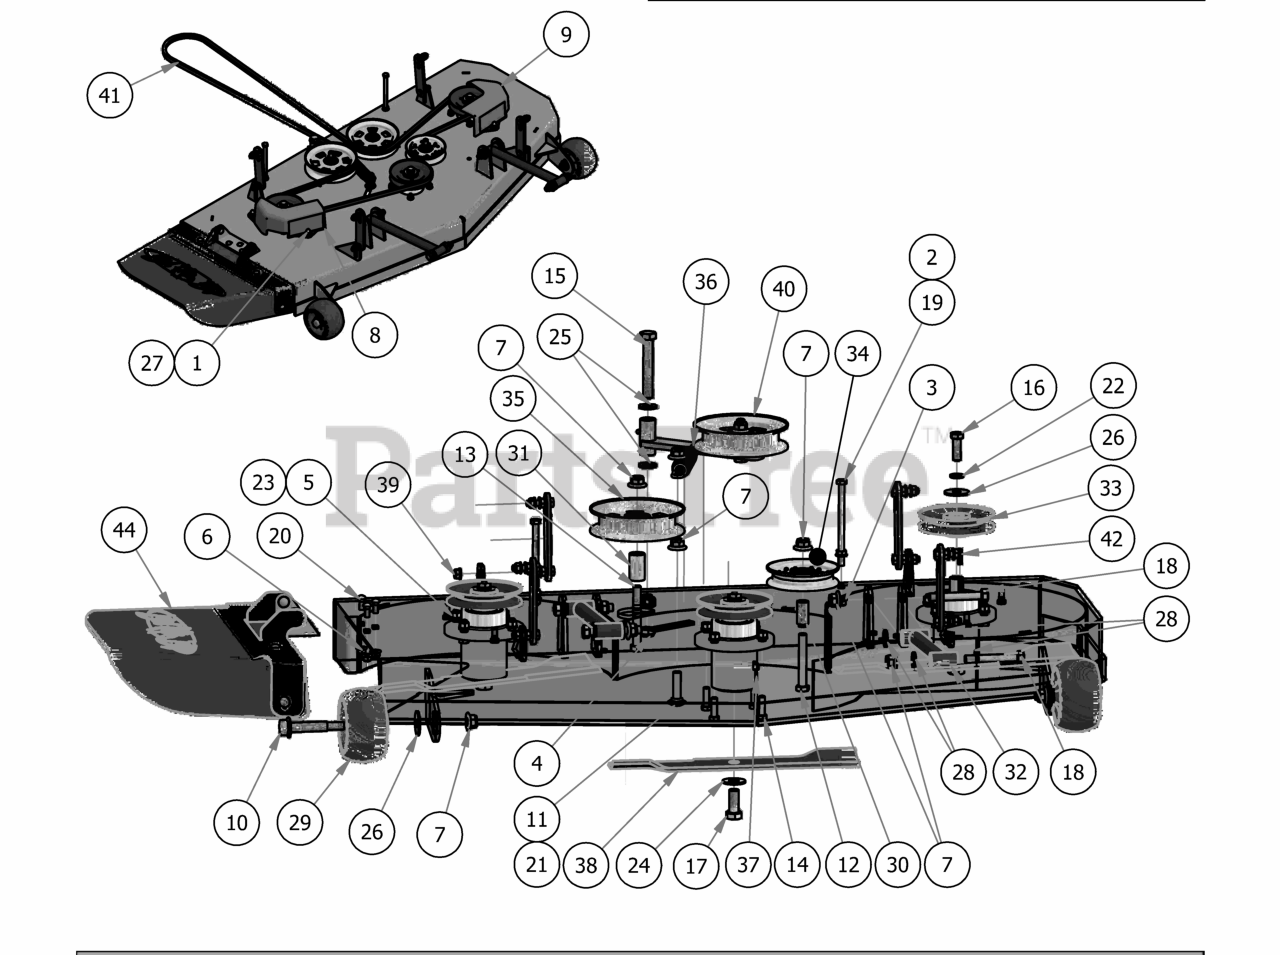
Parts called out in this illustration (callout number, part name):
1	Acorn nut-pulley Cover
2	3/8" Flange Nut
3	3/8" Nylock Flange Nut
4	5/8" Nylock (1/2 Jam)
5	3/8" Hex Nut
6	5/16" Nylon Flange Nut
7	1/2-13 Nylon Flange Nut
8	pulley cover chute side
9	pulley cover non-chute side
10	Deck Wheel Bolt
11	1/2 x 2" Carriage Bolt
12	1/2 x 3 1/2 Flange Bolt Grade 8
13	1/2" x 4" Bolt (Grade 8)
14	3/8" x 1 1/4" Hex Bolt
15	5/8" x 4" Hex Bolt
16	1/2"-20 x 1 1/2 - Grade 5 Fine Thread Bolt
17	5/8 x 1 1/2 Grade 8 Hex Bolt (Fine)
18	1/2-13 x 3 1/2 GR 5 Hex Bolt
19	3/8-16 x 5 1/2 Hex Bolt
20	5/16-18x3/4 carriage bolt
21	.517 Square Hole Round Washer
22	1/2" Lock Washer
23	3/8" Lock Washer
24	5/8'' Flat Washer
25	.630 ID Plastic Washer
26	1/2" Belleville Washer
27	.360 ID Plastic Washer-Black
28	.505 Nylon Spacer
29	Deck Wheel
30	.502 ID X .750 OD X 1.500 Long Spacer
31	1 3/4" Pulley Spacer
32	MZ/ZT Deck Locator
33	MZ Deck Pulley
34	4-3/4 Idler Pulley
35	5-3/4 Idler Pulley
36	Deck Idler Spring
37	Spindle Assembly-MZ
38	48" High Lift Fusion Blade
39	Deck Hanger Assembly
40	2017 54"/48" Deck Idler Assembly
41	B147 Deck Belt
42	3/16 x 1 Square Key
43	48" Welded Deck Shell
44	MZ Discharge Chute Assembly
